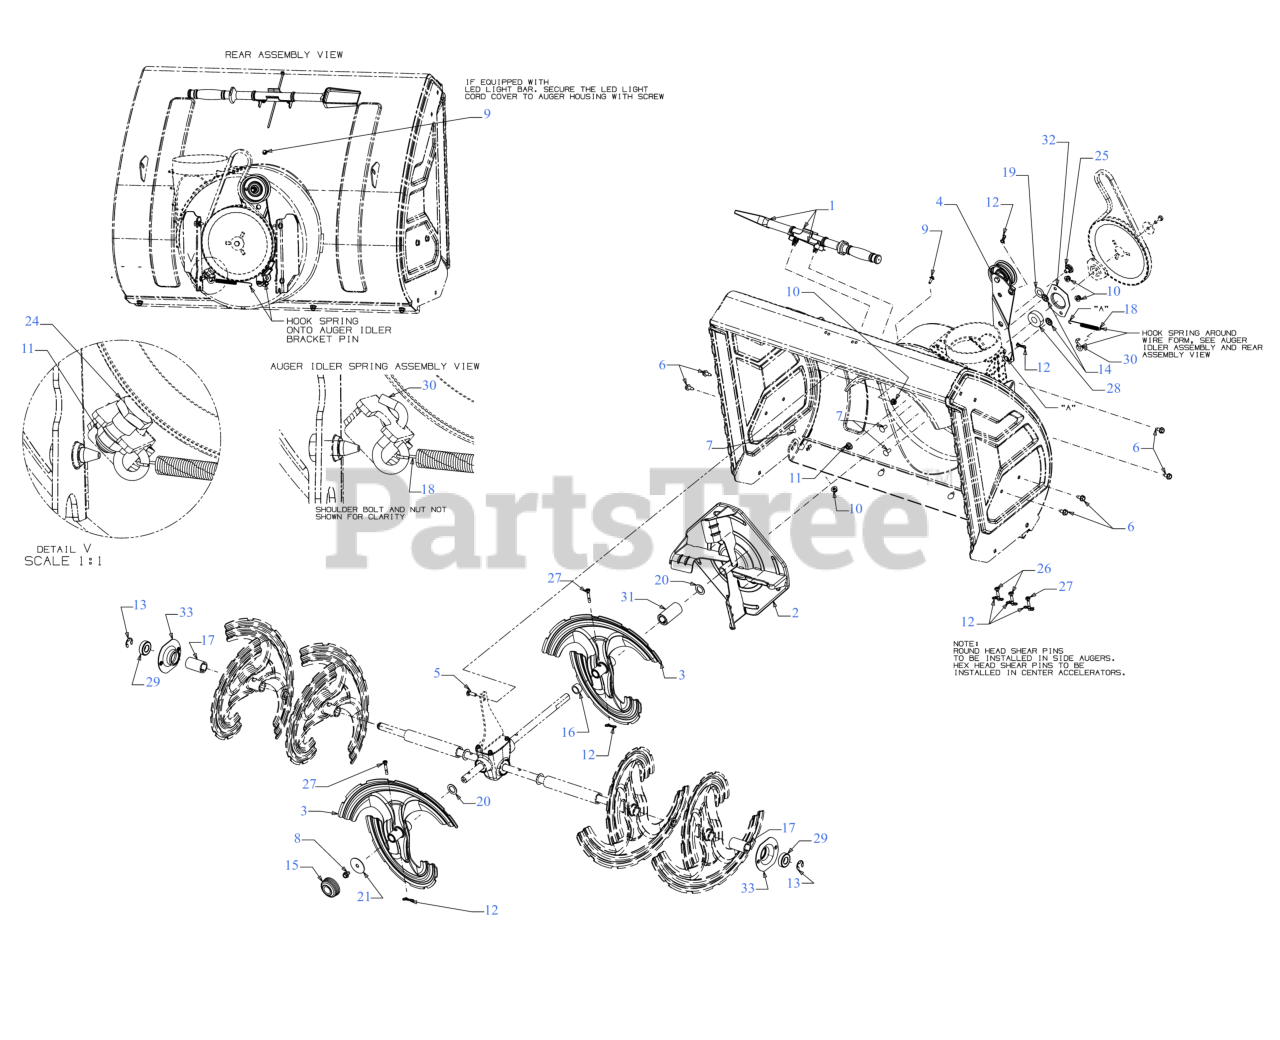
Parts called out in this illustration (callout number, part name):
1	CLEANOUT TOOL
1	CLEANOUT TOOL MOUNTING CLIP
4	IDLER ASSEMBLY
5	CARRIAGE BOLT 5/16-18 x 1.00
6	SCREW 5/16-18 x .750
7	CARRIAGE BOLT 5/16-18 x .75
8	SCREW 5/16-18 x .500
9	SCREW M6-1 x .625
10	FLANGE LOCK NUT 5/16-18
12	BOW TIE COTTER PIN 1/4-5/16
13	E-RING
14	PUSH NUT
17	SPACER 1.25 x .75 x 2.085
18	EXTENSION SPRING .38 OD x 4.59
19	FLAT WASHER
20	FLAT WASHER .793 ID X1.240X.06
21	HUB CAP WASHER .406 x 1.92 x .060
24	SHOULDER SCREW .498 DIA x .340
25	SHOULDER SCREW .625 DIA x .163
26	SHEAR PIN (.25 x 1.50)
26	Cub Cadet SHEAR PINS (3X SNOW)
27	SHEAR PIN (.25 x 1.5)
27	Cub Cadet SHEAR PINS (3X SNOW)
28	BEARING W/OUT COLLAR
29	BALL BEARING
30	ROD SPRING HOOK
32	BEARING HOUSING 1.85 ID
